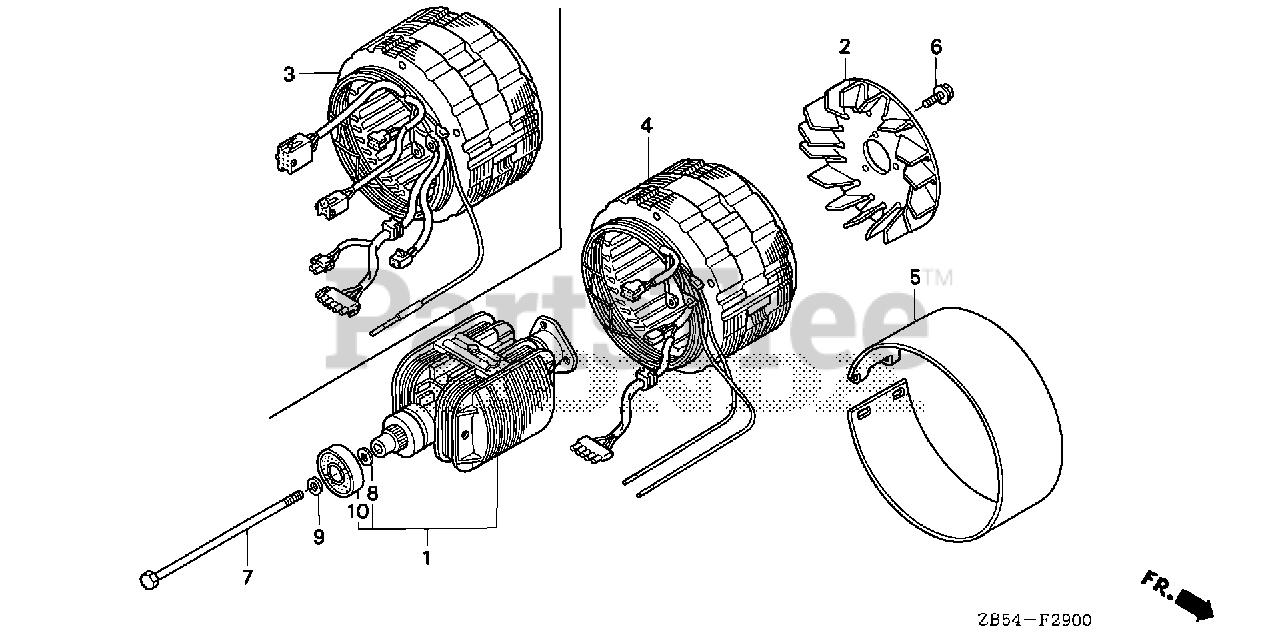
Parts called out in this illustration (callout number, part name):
1	ROTOR (701)
4	STATOR ASSY. (NOT AVAILABLE)
5	COVER, STATOR
6	SCREW, TAPPING (5X14)
7	BOLT, HEX. (10X281)
8	WASHER, THRUST
9	WASHER, PLAIN (10MM)
10	BEARING ASSY. (6205)
